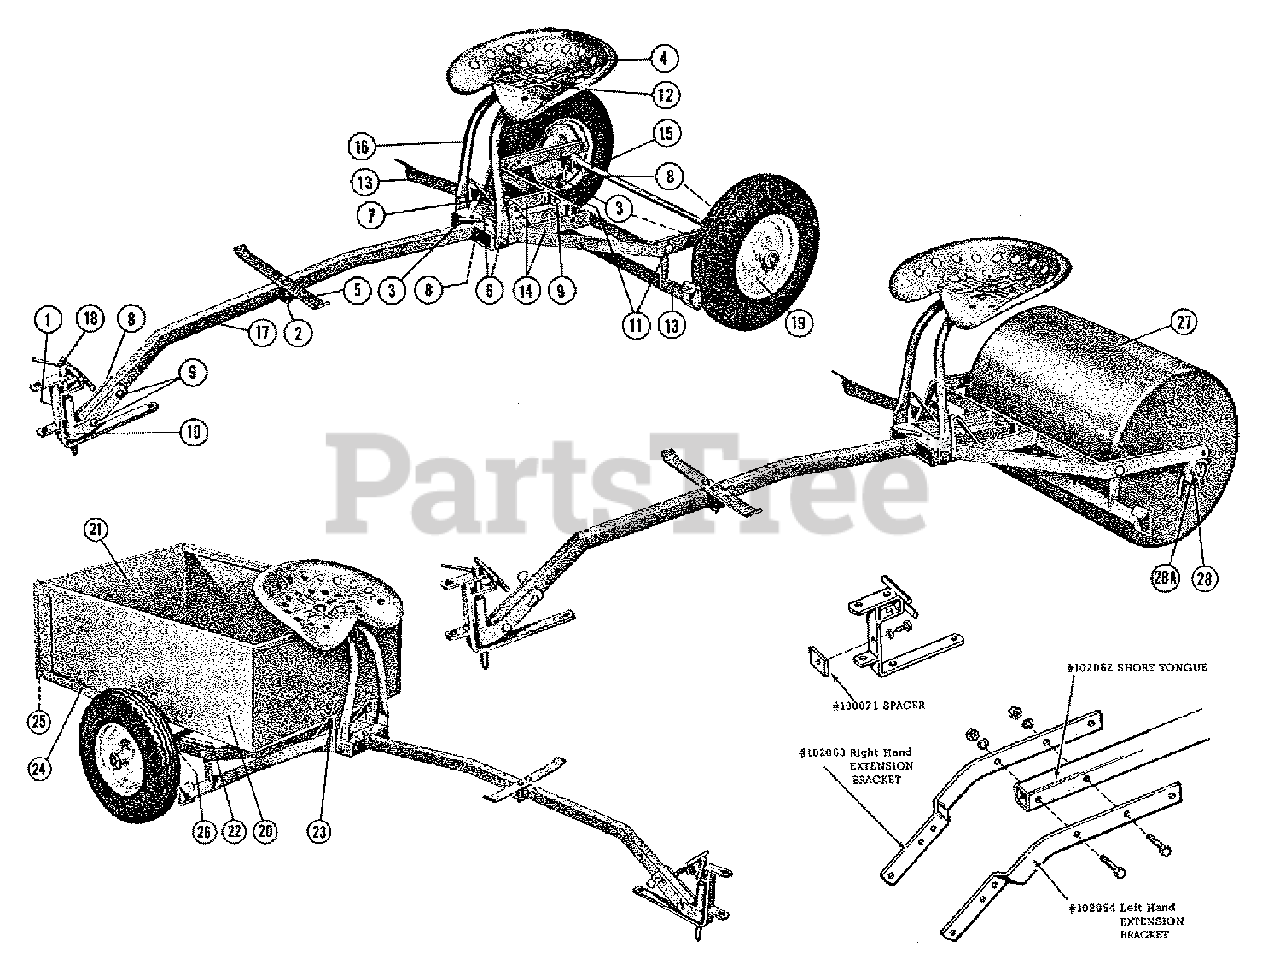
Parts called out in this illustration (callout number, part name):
1	FRAME EXTENSION
2	FOOT REST CLAMP
3	PIN, Tongue
5	FOOT REST
7	SPRING, Brake
8	CLIP, Spring
9	PIN, Tongue
10	CLEVIS ASSEMBLY
12	PLATE, Seat
13	BRAKE ASSEMBLY
14	FRAME ASSEMBLY
15	AXLE ASSEMBLY
16	SEAT SUPPORT
18	HITCH PIN ASSEMBLY
19	WHEEL, Only, 4" Hub, 3/4" Axle, Less Tire
19A	TIRE, 4.00 x 8 Rib Tread
19B	TUBE, 4.00 x 8
20	TRAILER BODY
23	PLATE, Box Guide
24	BOX PIVOT ASSEMBLY
26	CLIP, Spring
27	ROLLER, Lawn
28	BUSHING (Nylon)
28A	RETAINER, Bearing
